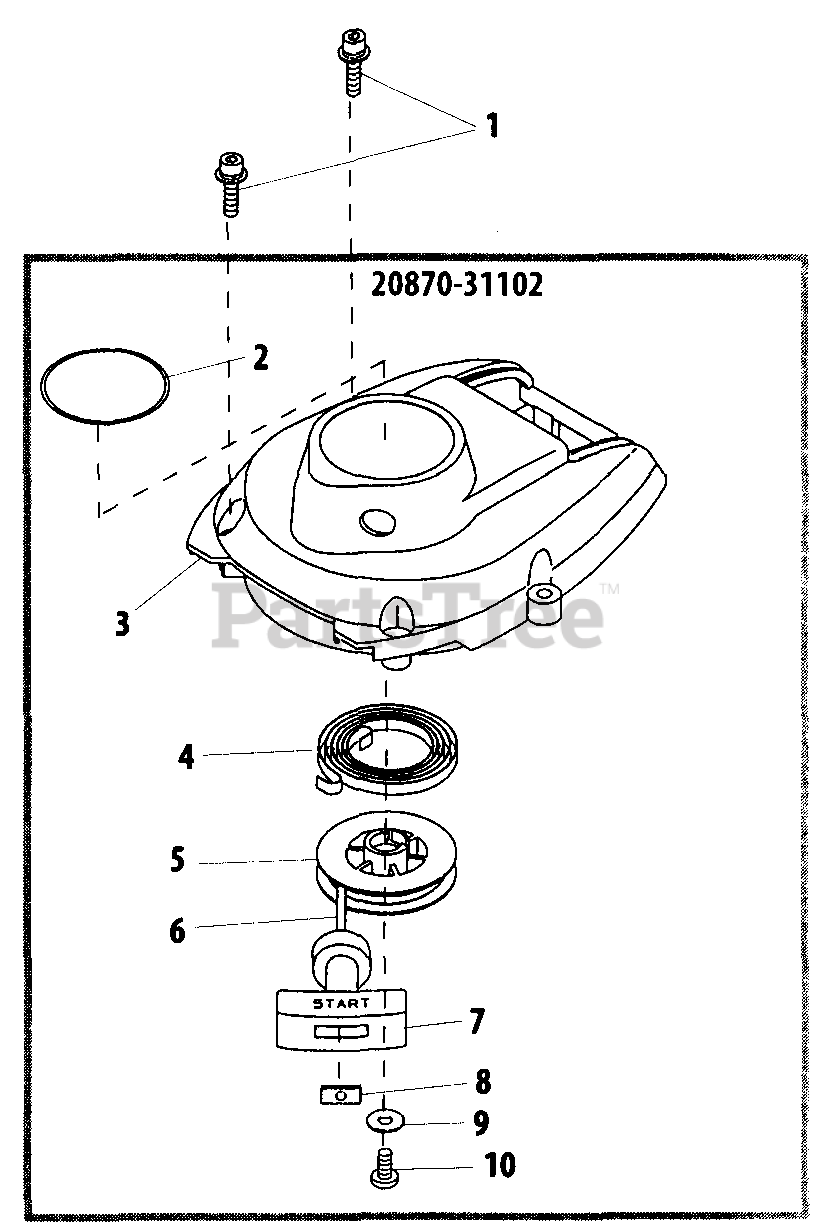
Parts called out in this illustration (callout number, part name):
1	SCREW - 5X20
2	LABEL - IDENTIFICATION
3	COVER, FAN
4	SPRING, REWIND
5	REEL, ROPE
6	ROPE, STARTER
7	GRIP, STARTER
8	RETAINER, ROPE
9	WASHER
10	SCREW
20870-31102	STARTER ASSY
